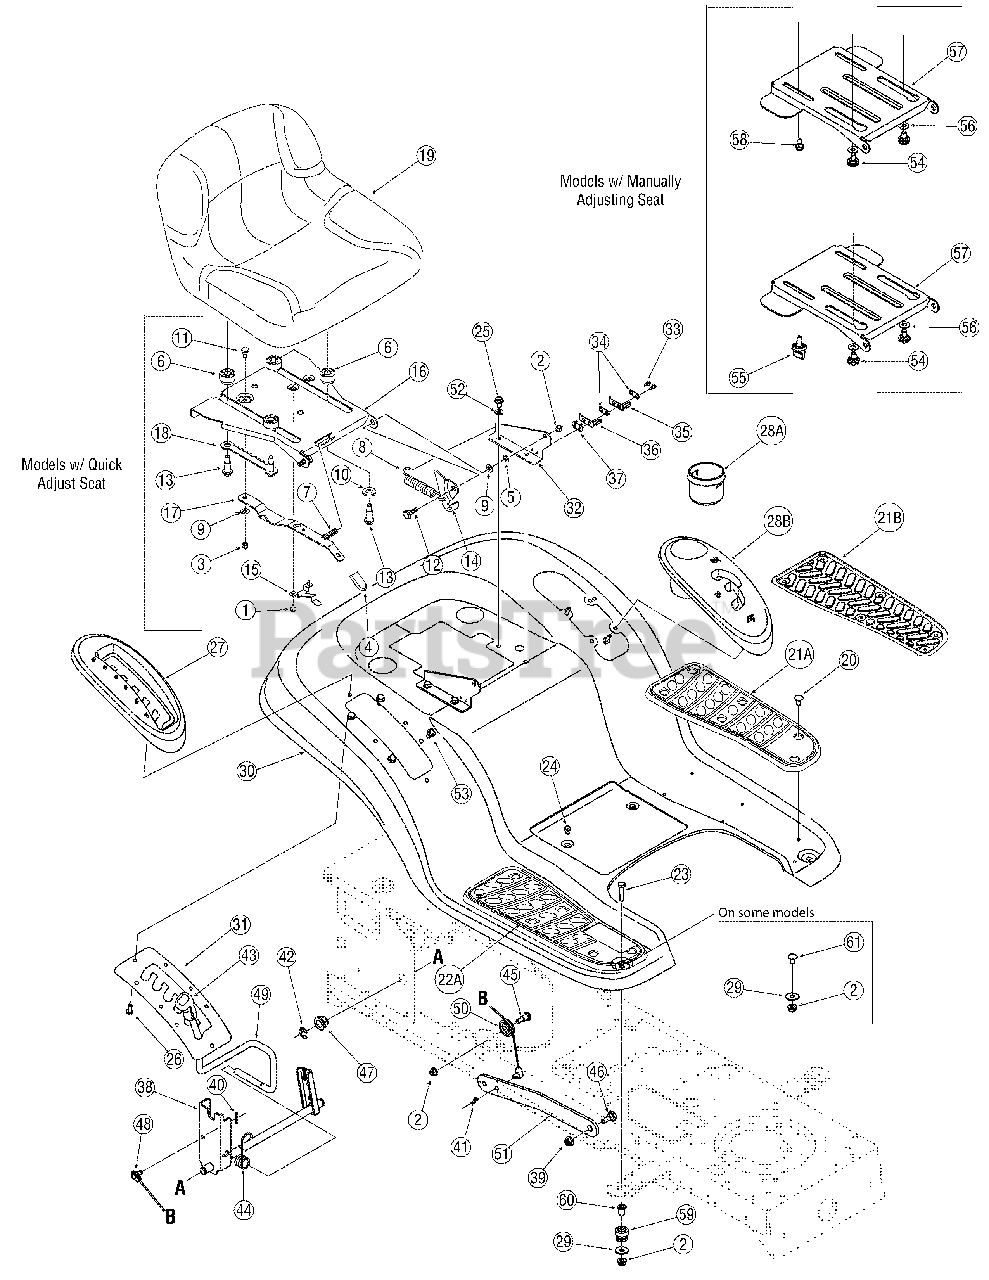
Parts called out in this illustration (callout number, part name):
1	Screw, #10-16 x.375
2	Nut, Flange Lock, 5/16-18, GrF
3	Nut, Flange Lock, 1/4-20
4	Seat Adjuster Grip
5	Nut, Speed,.3125 ID
7	Compression Spring,.41 x 1.5
8	Spring, Extension,.84 Dia. x 4.6
9	Wash, Flat, .340 x .688 x .065
10	Wash, Flat,.531x 1.062 x.134
11	Screw, Shld, .340 x.285, 1/4-20
12	Screw, Shoulder,.437 x.268
13	Screw, Should,.50 x.925, 3/8-16
14	Seat Bracket, Lift
15	Seat Stop
18	Seat Adjustment Selector
19	Low Back Seat
19	Medium Back Seat
20	Ratchet Clip
23	Hex Screw, 5/16-18 x 1.25
24	Screw, 1/4-20, 0.500
25	Screw, 5/16-18, 0.625
26	Screw, 1/4-15, 0.750
27	Cover, Lift Lever
29	Washer, Flat,.344 x 1.0 x.063
33	Screw, #8-18 x.50
34	Plate, Insulator
35	Spring Switch, Outer
36	Spring Switch, Inner
37	Plate, Insulator Boss
40	Pin, Cotter,.072 Dia. x 1.13
41	Pin, Cotter, 3/32, 1.0
42	Ring, E Type,.625 Dia.
43	Grip, Handle, 1/2
44	Spring, Torsion
45	Screw, 5/16-18 x.620 Gr2
46	Scr.,Shldr, .625 x.165,(42" Deck)
46	Screw, Shld,.50 x.27, (46" Deck)
47	Bearing, Hex Flange
48	Cable, Lift, 16.16
49	Handle, Lift
50	Pulley, Roller
52	Lock Washer, 5/16
53	Scr5/16-18 x.750 (7-Style)
53	Screw, 5/16-18, 0.625
54	Shoulder Screw
55	Knob, 3/8-16
56	Flat Washer, .406 x .875 x .059
58	Hex Head Washer Screw, 3/8-16
59	Grommet, .4375 x .750
60	Flanged Spacer
61	Carriage Bolt, 5/16-18 x .750
